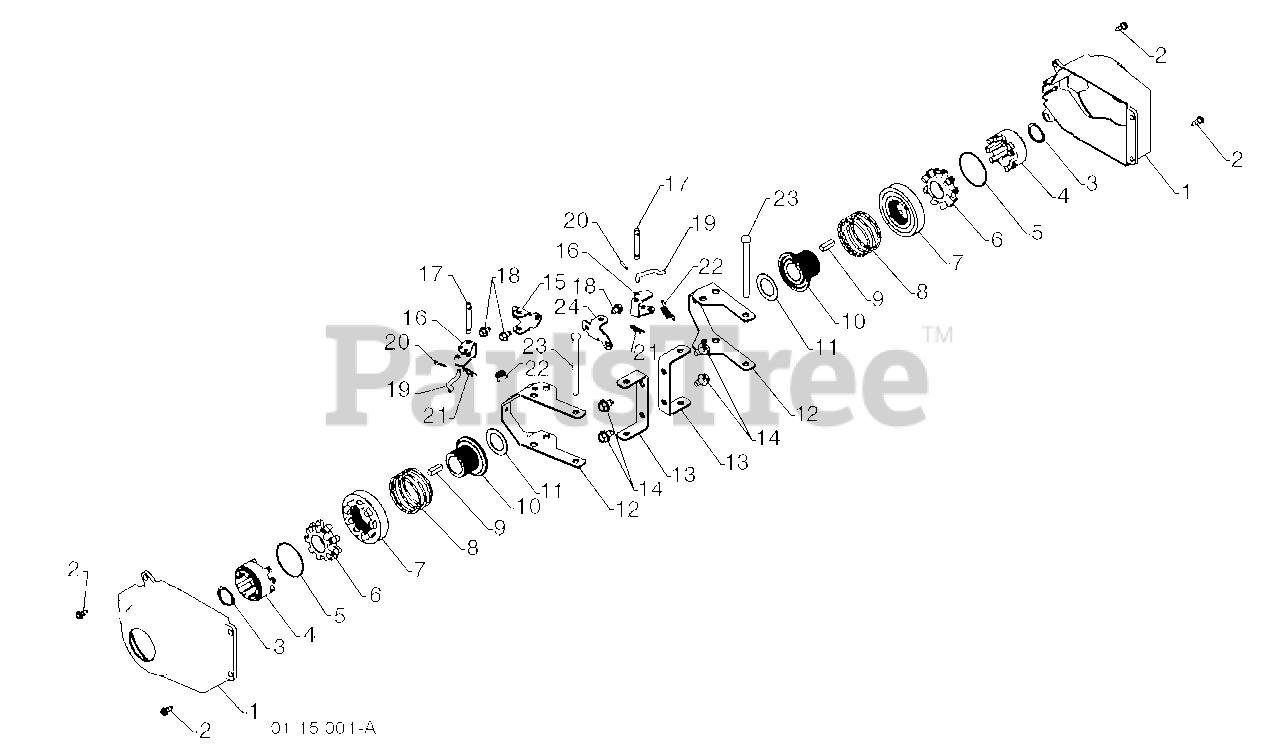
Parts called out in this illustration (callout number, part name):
2	SHOULDER SCREW
3	RETAINER RING
4	WHEEL DRIVER
5	RETAINER RING
6	WHEEL LOBE
7	CLUTCH SLIDE
9	SQUARE KEY
10	AXLE LOBE
11	THRUST WASHER
12	STEERING YOKE
13	STEERING BRACKET
14	SCREW 5/16-18 X .50
15	PIVOT BRACKET
16	BELLCRANK
17	BELLCRANK PIN
18	SCREW 1/4-20 X .375
19	STEERING LINK
24	PIVOT BRACKET
